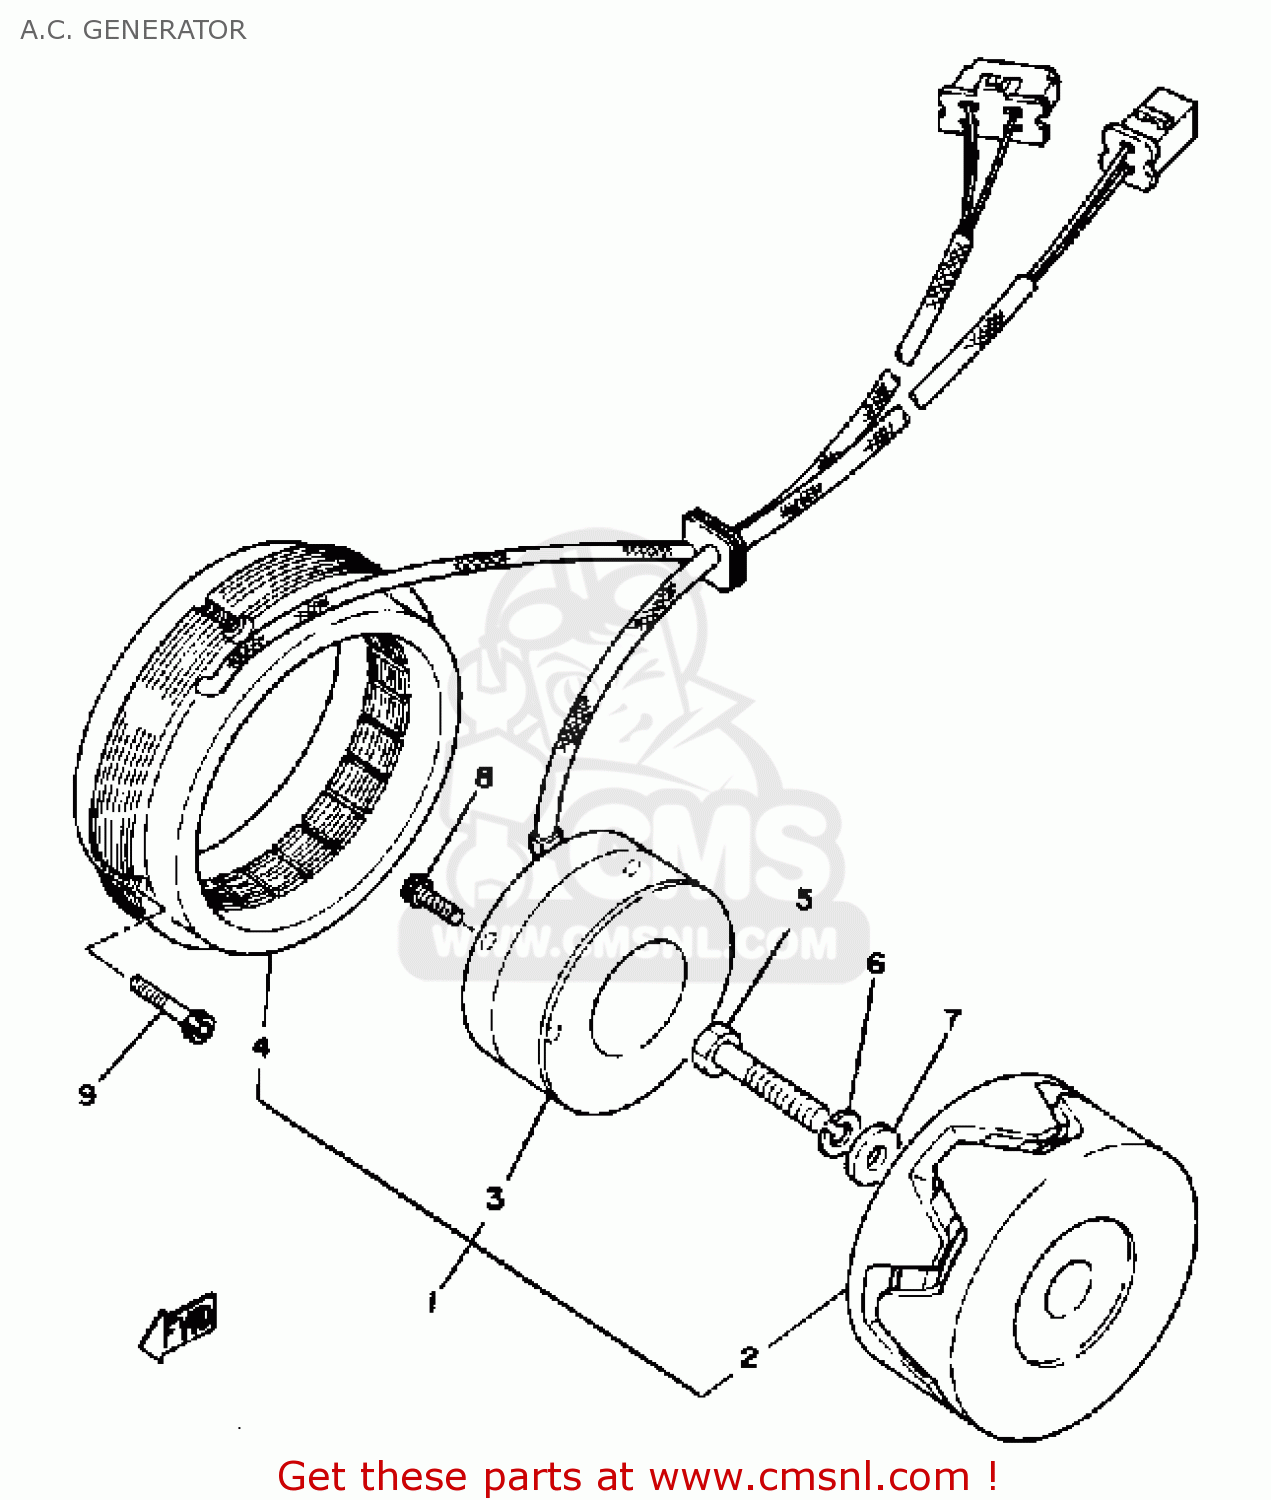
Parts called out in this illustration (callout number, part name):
1	A.C. GENERATOR ASSY
2	ROTOR ASSY
3	FIELD COIL ASSY
4	STATOR ASSY
5	BOLT (341)
6	YBS67-10 WASHER, SPRING
7	WASHER, PLATE(52H)
8	BOLT (2H7)
9	BOLT, HEXAGON SOCKET HEAD(1VJ)
